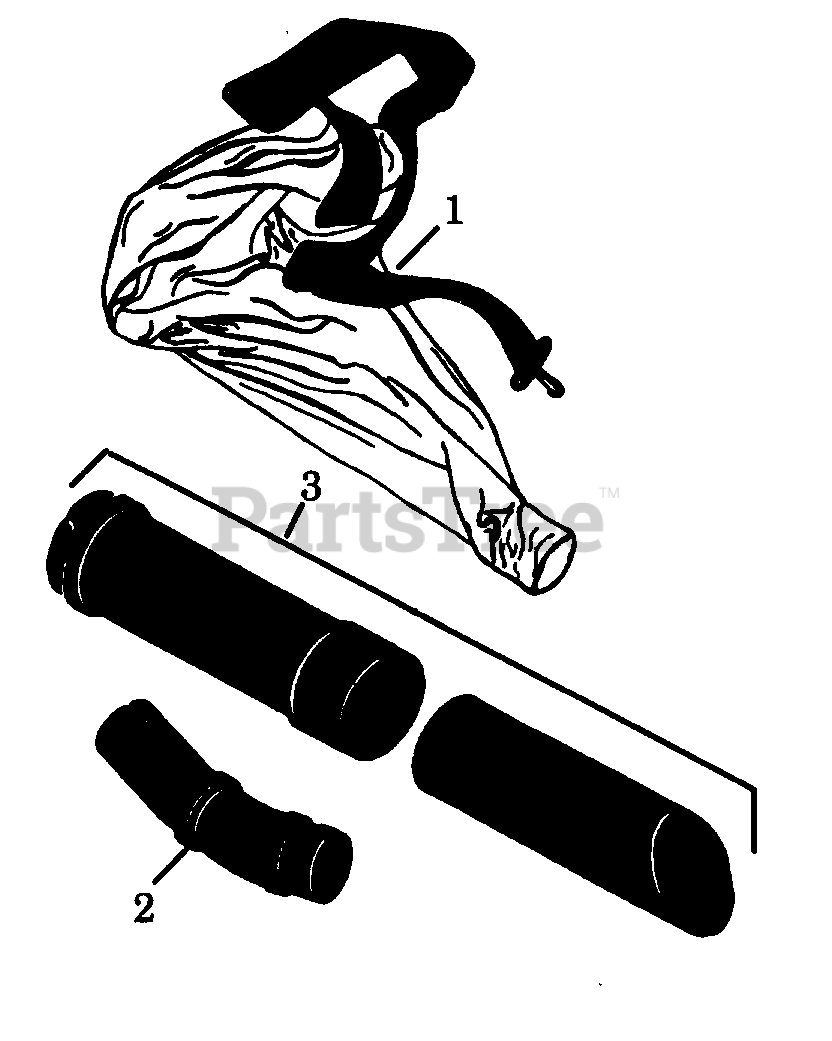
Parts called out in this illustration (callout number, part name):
1	Collection Bag W/Strap
2	Collection Bag Elbow Tube
3	Vacuum Tubes
